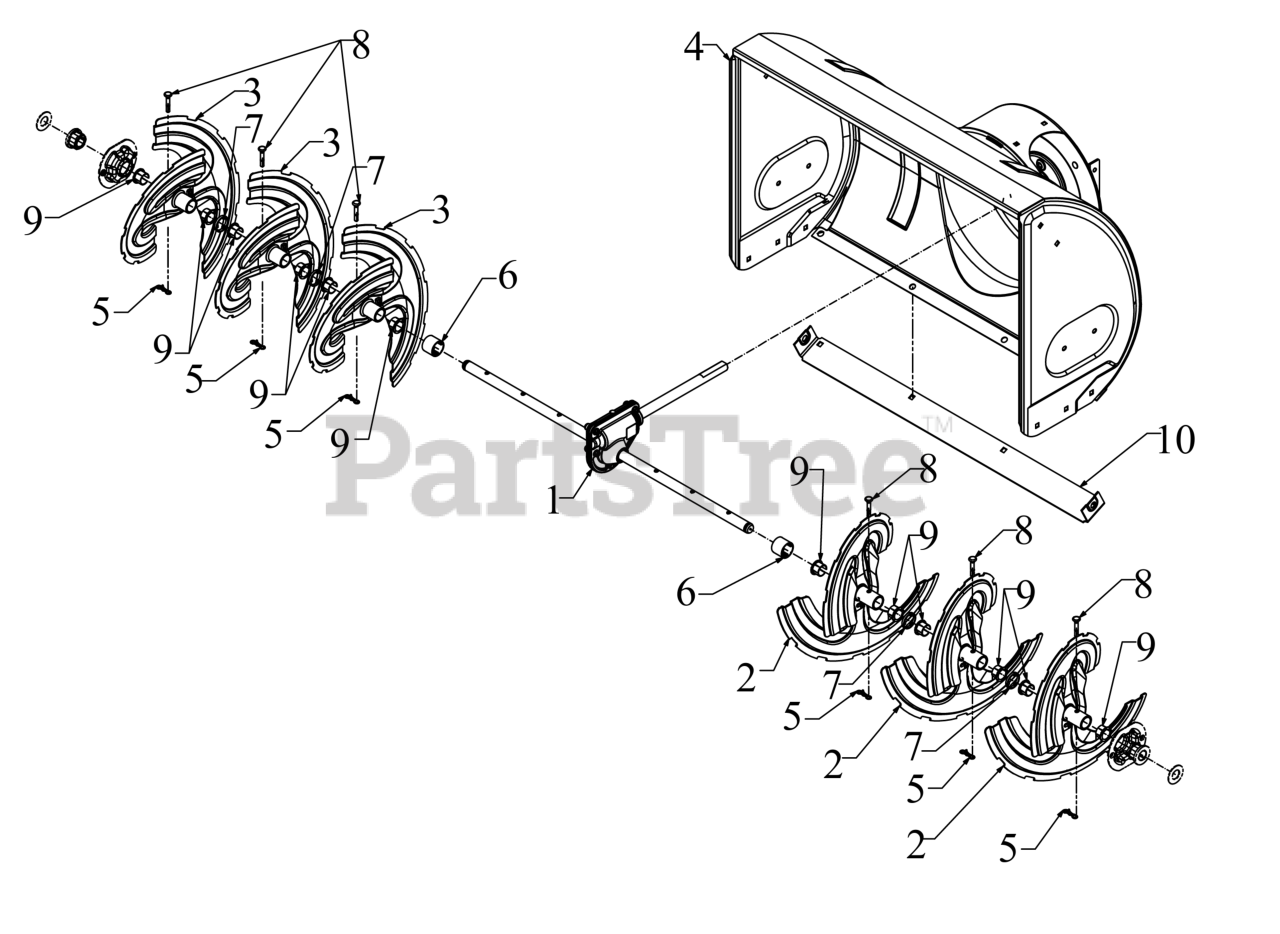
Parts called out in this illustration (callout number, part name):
1	30" GEARBOX ASSEMBLY
5	BOW TIE COTTER PIN 1/4-5/16
6	SPACER 1.25OD x .75ID X1.00 LG
7	SPCR 1.25 OD x 75IDX2.00LG
8	SHEAR PIN .25 x 1.50 GR2
8	Cub Cadet SHEAR PINS (2X SNOW)
8	SHEAR PINS QTY 4
9	FLANGE BUSHING
